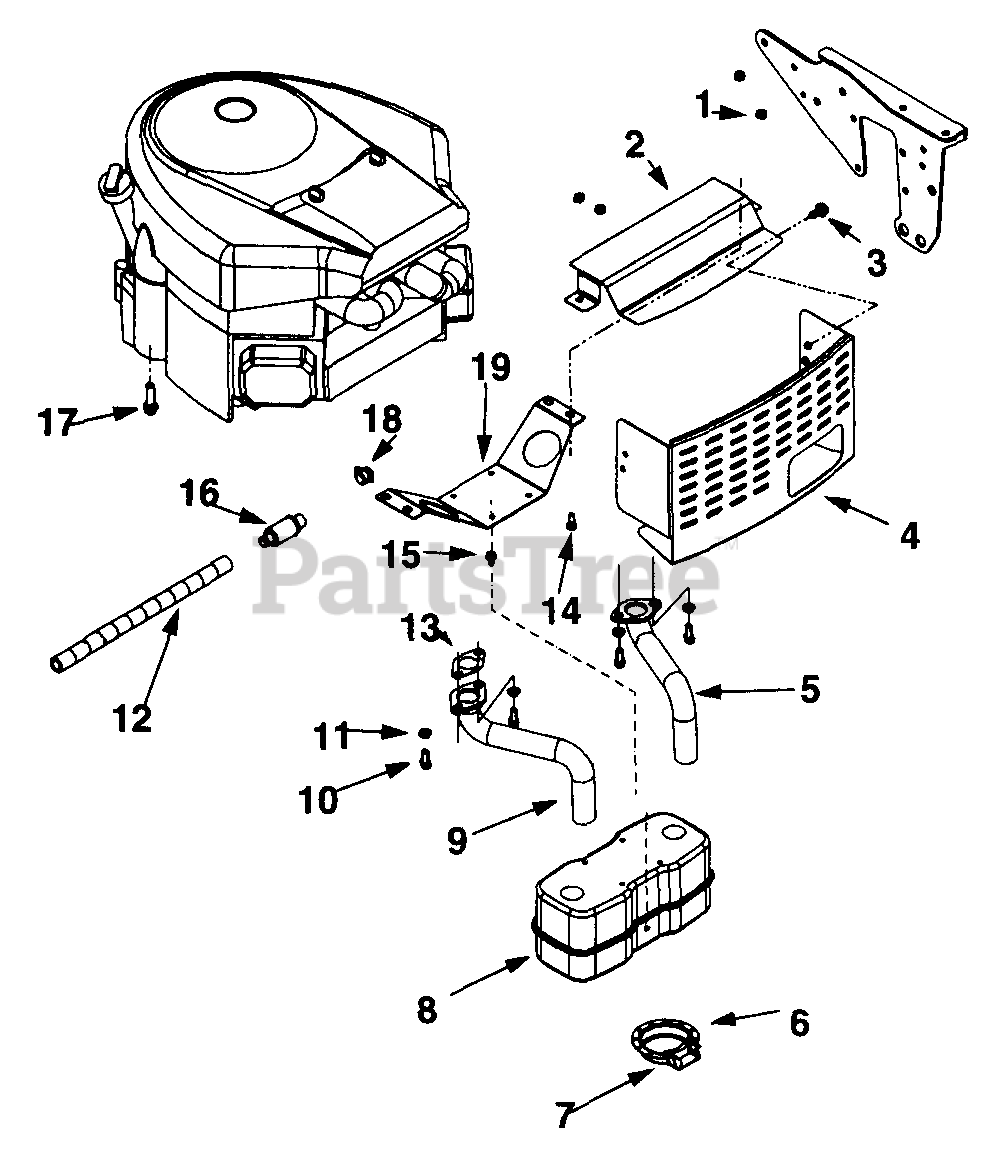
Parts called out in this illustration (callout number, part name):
1	Hex Sems Nut 1/4-20 Thd.
2	Front Heat Shield
3	Hex TT-Tap Scr. 5/16-18 x .62" Lg.
6	Hex Hd. F-Tap Scr. #8-32 x .38" Lg.
7	Muffler Deflector
8	Muffler
9	Exhaust Tube - R.H.
10	Hex Bolt 5/16-18 x .625" Lg.
11	L-Wash. 5/16" I.D.
12	Oil Drain Extension Hose
13	Exhaust Gasket
14	Hex Bolt 1/4-20 x .62" Lg.
15	Hex Wash. Hd. TT-Tap Scr. 1/4-20 x .5"
16	Oil Drain
17	Hex Wash. Hd. Scr. 3/8-16 x 1.25" Lg.
18	Oil Drain Cap
19	Muffler Mounting Brkt.
